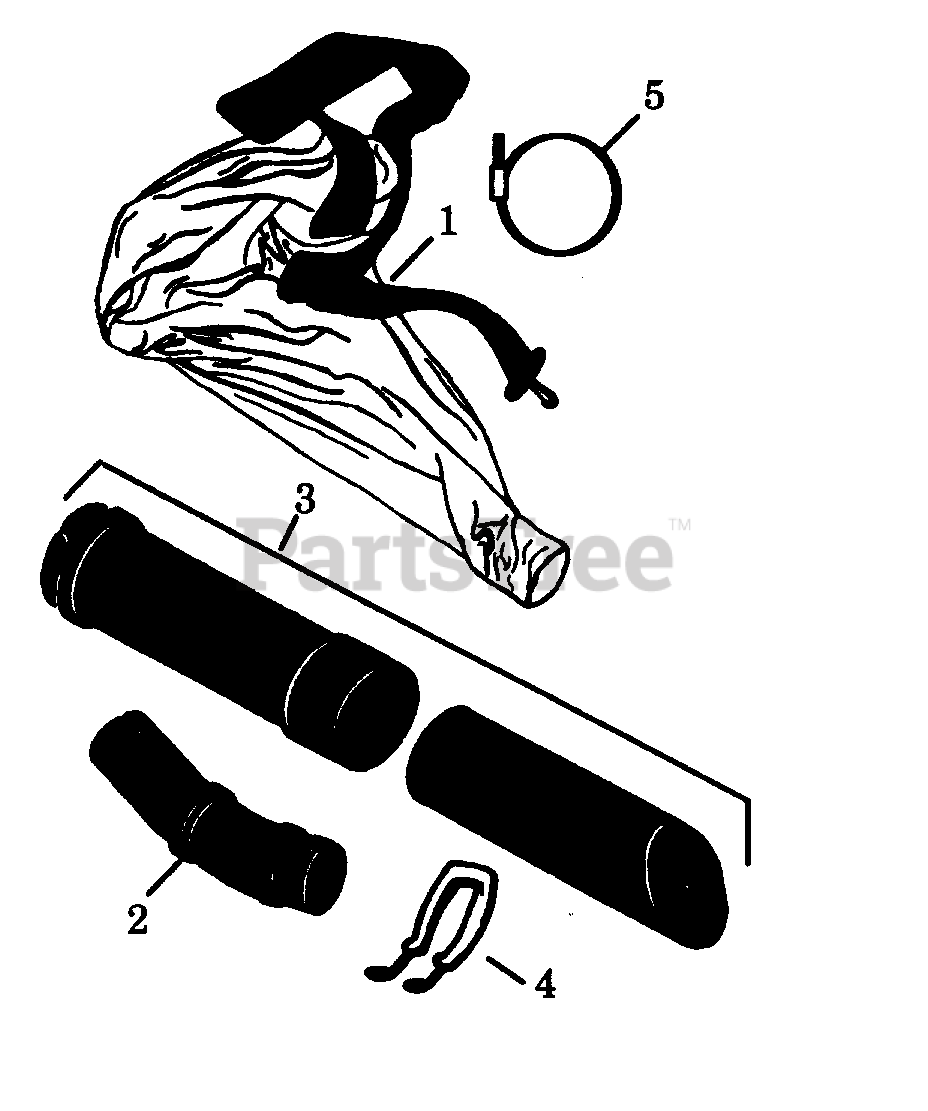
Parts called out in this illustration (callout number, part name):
1	Collection Bag W/Strap
2	Collection Bag Elbow Tube
3	Vacuum Tubes
